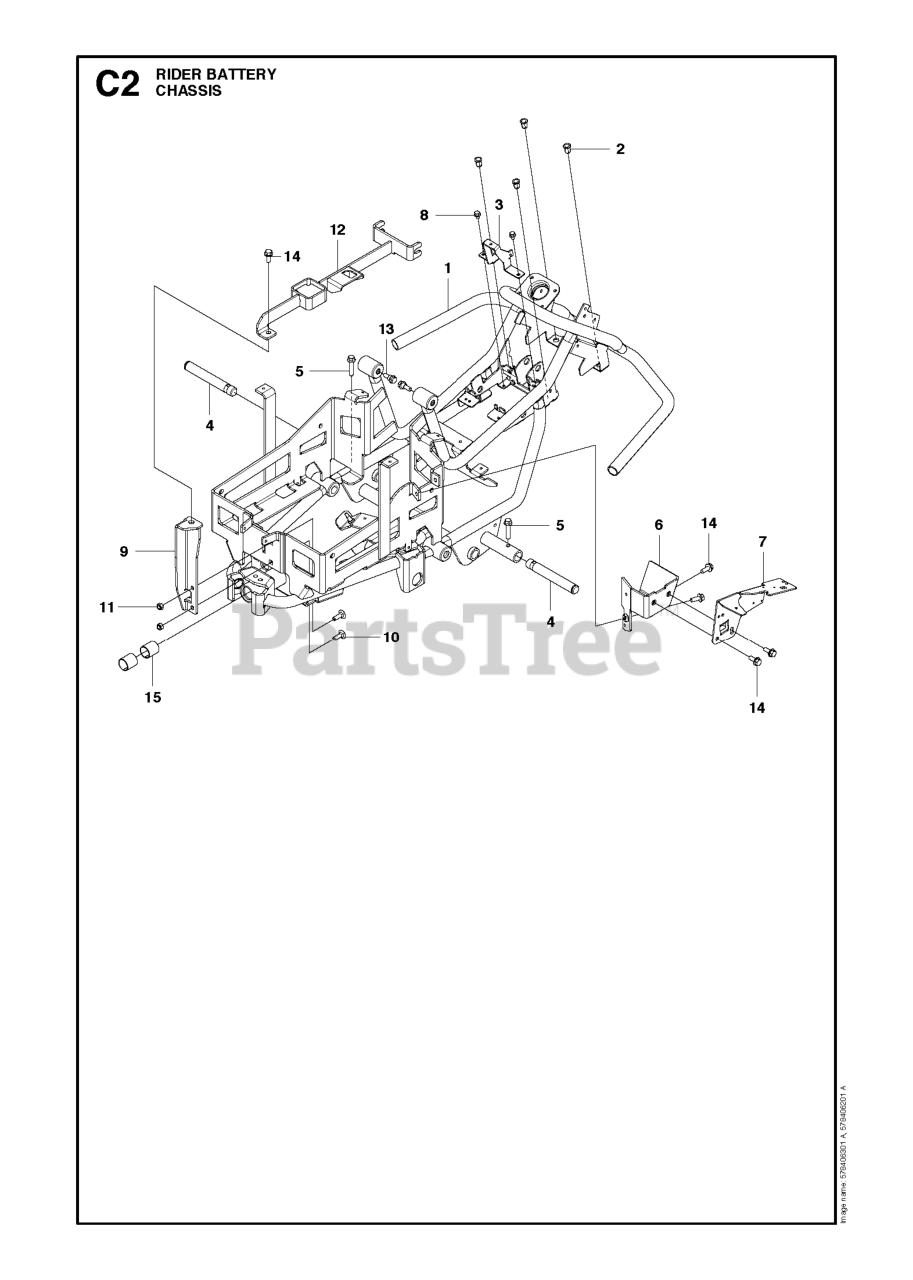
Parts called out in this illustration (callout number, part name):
5	BOLT FLANGE - M8X40\
11	LOCKNUT M8
15	BUSHING
